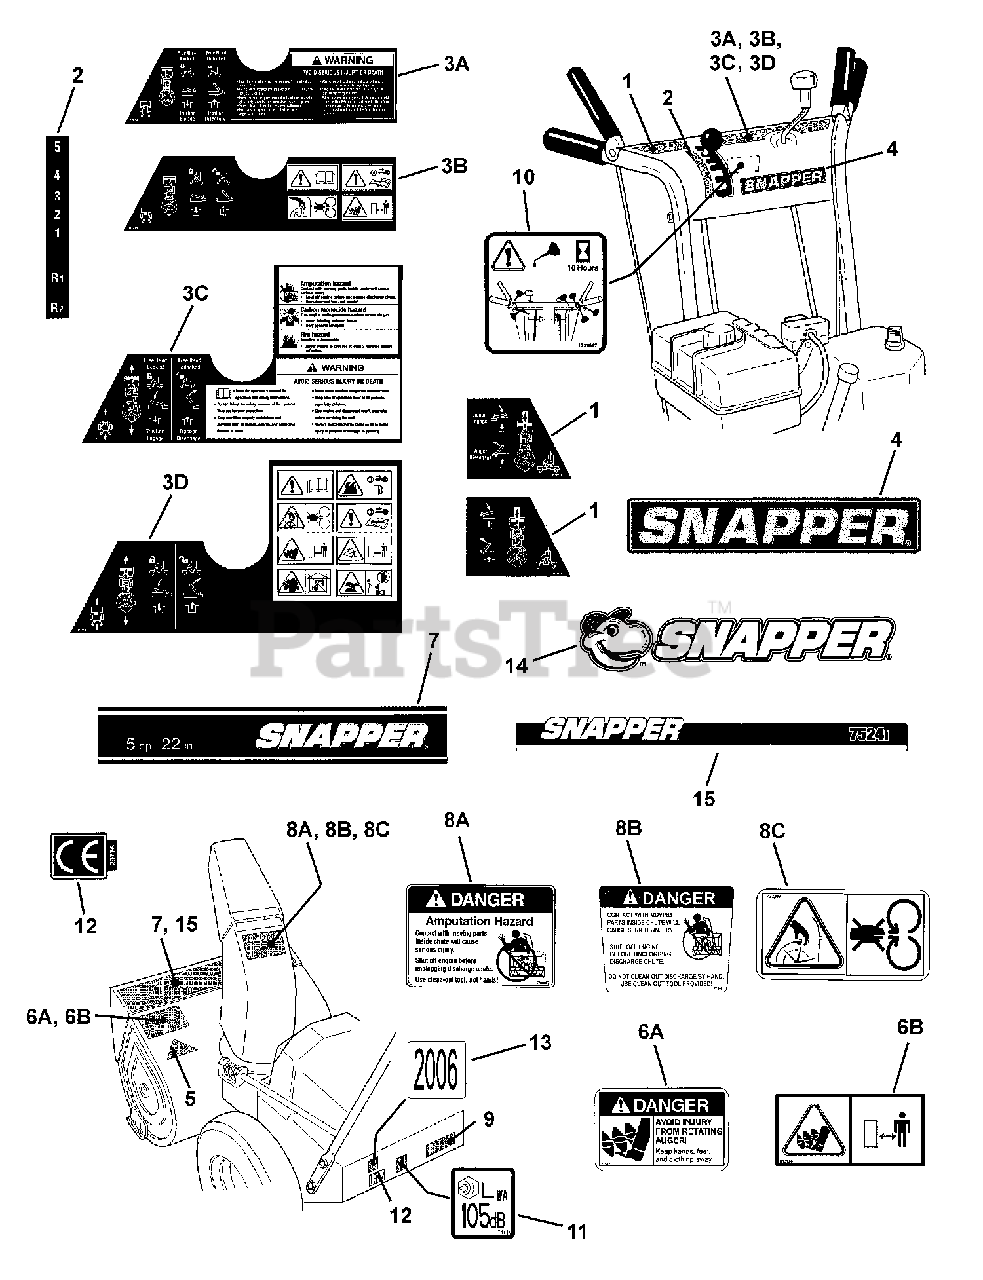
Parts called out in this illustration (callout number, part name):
1	DECAL, Dashboard- RH
1	DECAL, Dashboard- RH- Euro
2	DECAL, Shift Pattern
3A	DECAL, Dashboard- LH
3B	DECAL, Dashboard- LH- Euro
3C	DECAL, Dashboard, Top, LH
3D	DECAL, Dashboard, Top, LH (Euro)
4	DECAL, Dash Front - SNAPPER
5	*DECAL, OPEI
6A	DECAL - Danger, Auger
6B	DECAL, CE- Auger Warning
7	DECAL, Stripe- SNAPPER (5hp, 22")
8A	DECAL, Danger, Chute/Deflector
8B	DECAL, Danger, Chute/Deflector
8C	DECAL, Chute Warning
9	*I.D. Tag
10	DECAL, Lube- Controls
11	DECAL, Sound 105
12	DECAL, Euro Community (CE)
13	DECAL, 2006 Year of Manufacture
14	DECAL, Dash Front- Snapper
15	DECAL, Stripe- Snapper (7.5 24")
